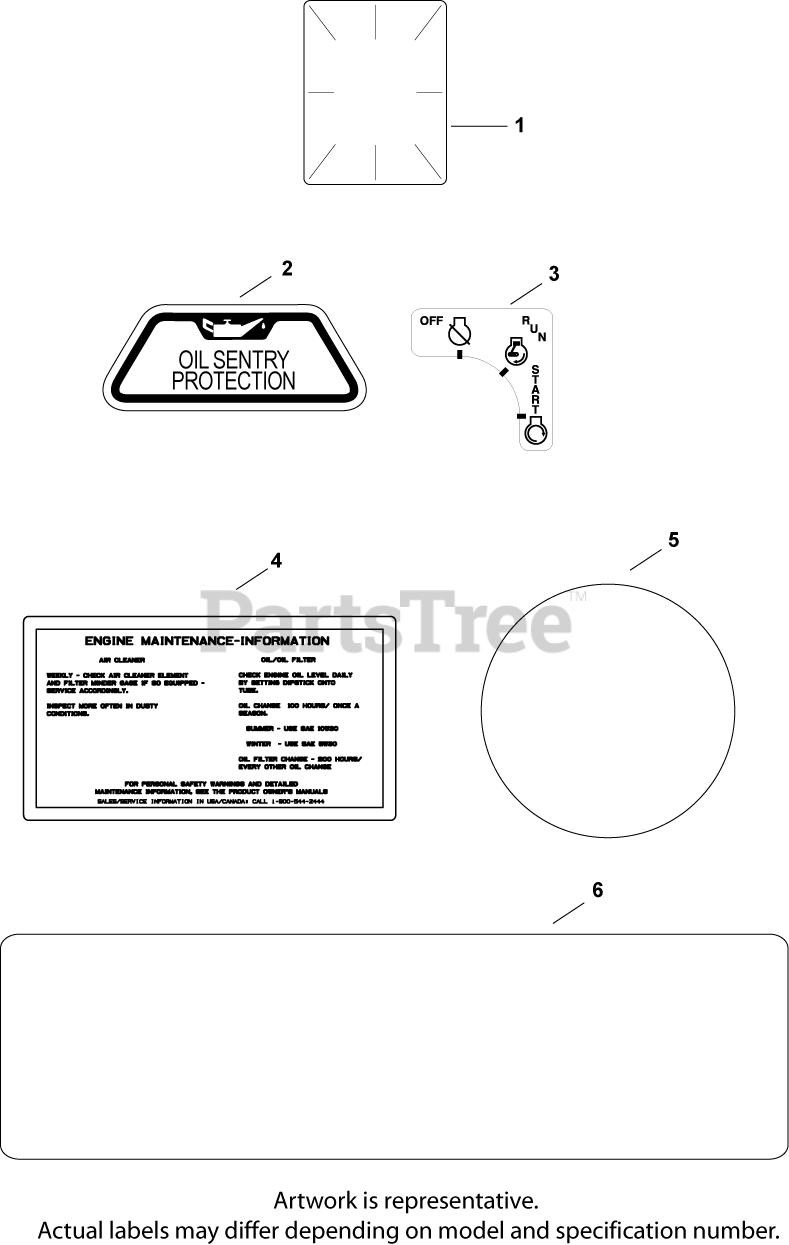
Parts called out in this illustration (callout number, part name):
1	DECAL, CLEAR LAMINATE USE 25 113 70-S
2	DECAL, OIL SENTRY - (#DSC)
3	DECAL, KEY SWITCH
4	DECAL, AIR CLEANER - (#DSC)
5	LABEL, (ROUND KOHLER GOLD)-USE 24 113 18
6	DECAL, 23 HP - (#24113216S)
